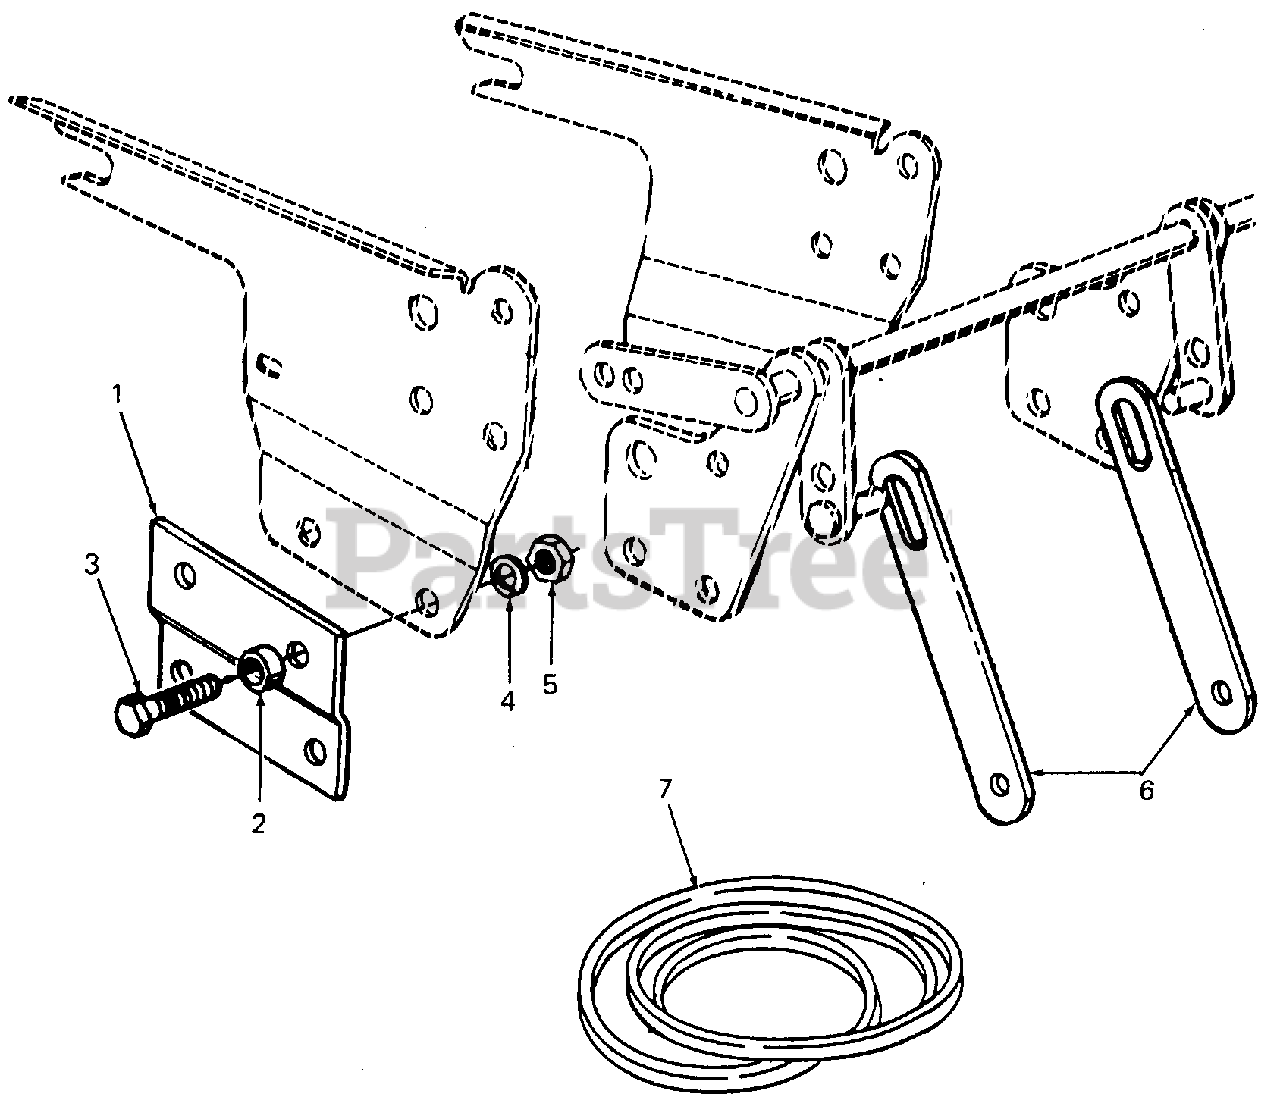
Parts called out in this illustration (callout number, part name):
3	Screw, Hex Cap, 5/8-18 X 1.31 Lg
4	Washer, Lock, 5/8
5	Nut, Hex Jam, 5/8-18
6	Link, Lift, 12.91
7	V-Belt, 89.0 in. Lg
